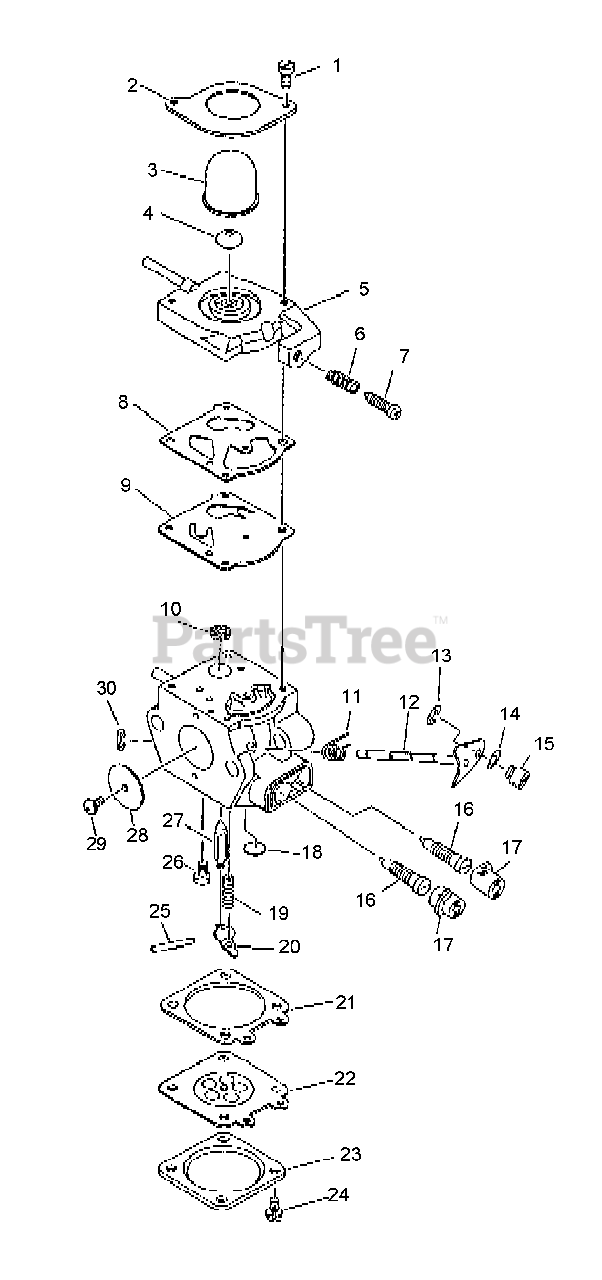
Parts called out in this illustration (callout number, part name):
1	SCREW, PUMP COVER
2	RETAINER, PURGE BULB
3	BULB, PURGE
4	VALVE, CHECK
5	BASE, PURGE
6	SPRING, IDLE ADJUST
7	SCREW, IDLE ADJUST
8	GASKET, PUMP
9	DIAPHRAGM, PUMP
10	STRAINER
11	SPRING, THROTTLE RETURN
12	SHAFT, THROTTLE
13	RING, RETAINING
16	NEEDLE - MIXTURE
17	CAP, LIMITER
18	PLUG, WELCH
19	SPRING, METERING LEVER
20	LEVER, METERING
21	GASKET, METERING
22	DIAPHRAGM, METERING
23	COVER, METERING
24	SCREW
25	SCREW
26	PIN, METERING LEVER
27	VALVE, INLET NEEDLE
28	VALVE, THROTTLE
30	RING, RETAINING
